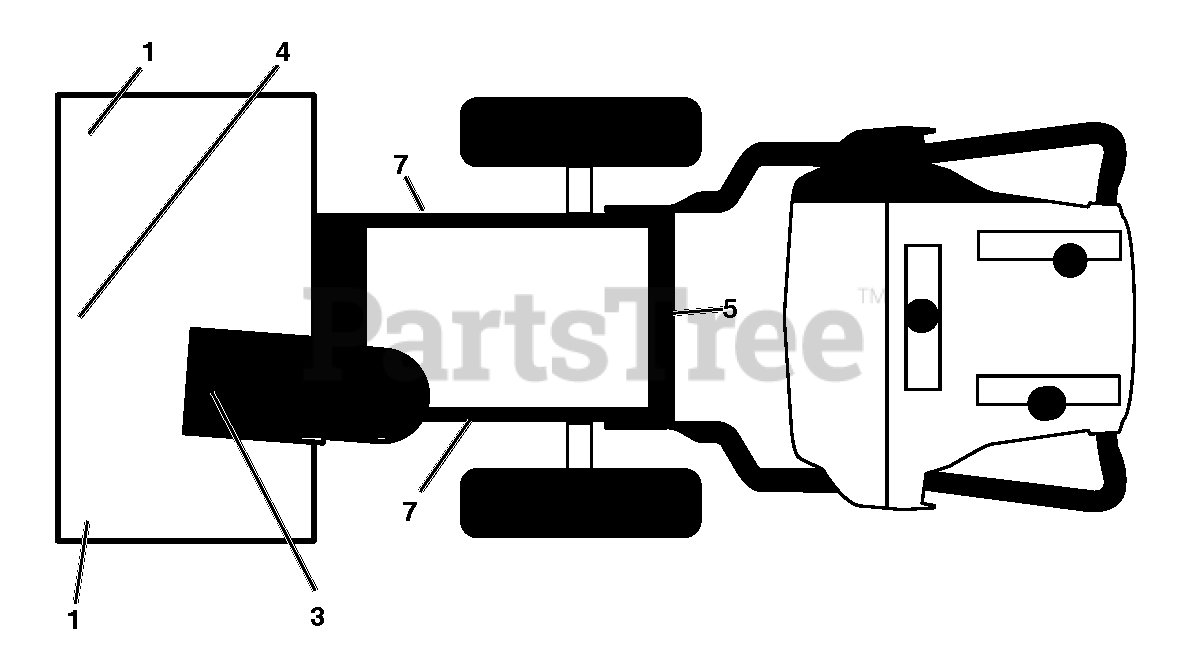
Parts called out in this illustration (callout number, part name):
1	DECAL.AUGER.SAFETY.
3	DECAL.CHUTE.SAFETY.
4	DECAL.AUGER."
5	Decal, Noise Level 105DB/CE EAC
7	DECAL.BELT.GUARD.
